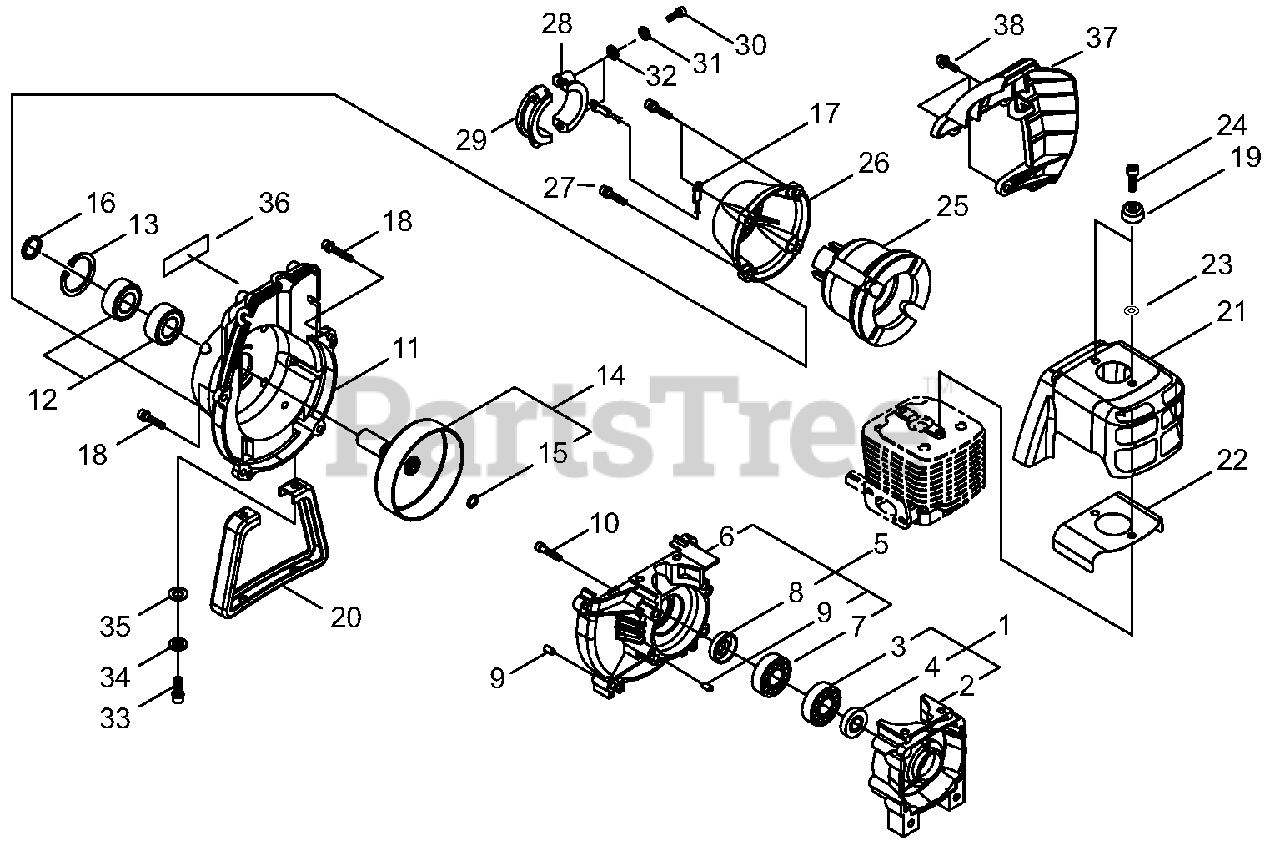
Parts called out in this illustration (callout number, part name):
1	CRANKCASE ASSY
2	CRANKCASE S
3	BEARING, BALL 6202 C3
4	SEAL, OIL 16
5	CRANKCASE ASSY, M
6	CRANKCASE M
7	BEARING, BALL 6202 C3
8	SEAL, OIL 16
9	PIN, LOCATING 5×10
10	BOLT 5×30
11	COVER, FAN
12	BEARING, BALL 6002 DDU
13	RING, SNAP Ø32
14	DRUM ASSY, CLUTCH
15	RING, SNAP Ø11.4
16	RING, SNAP
17	LEAD - GROUND
18	BOLT M5×20
19	COVER
20	STAND
21	COVER, ENGINE
22	SHIELD, HEAT
23	WASHER
24	BOLT M5×14
25	CUSHION, AV
26	CAP, CUSHION
27	BOLT M5×20
28	CLAMP - B
29	CLAMP - A
30	BOLT 5×25
31	WASHER, SPRING 5
32	WASHER, FLAT 5.5×10×0.8
33	BOLT 5×20
34	WASHER, SPRING 5
35	WASHER 5.5×12×0.8
36	LABEL, TRADE
37	GUARD, TOP
38	BOLT M4×16
